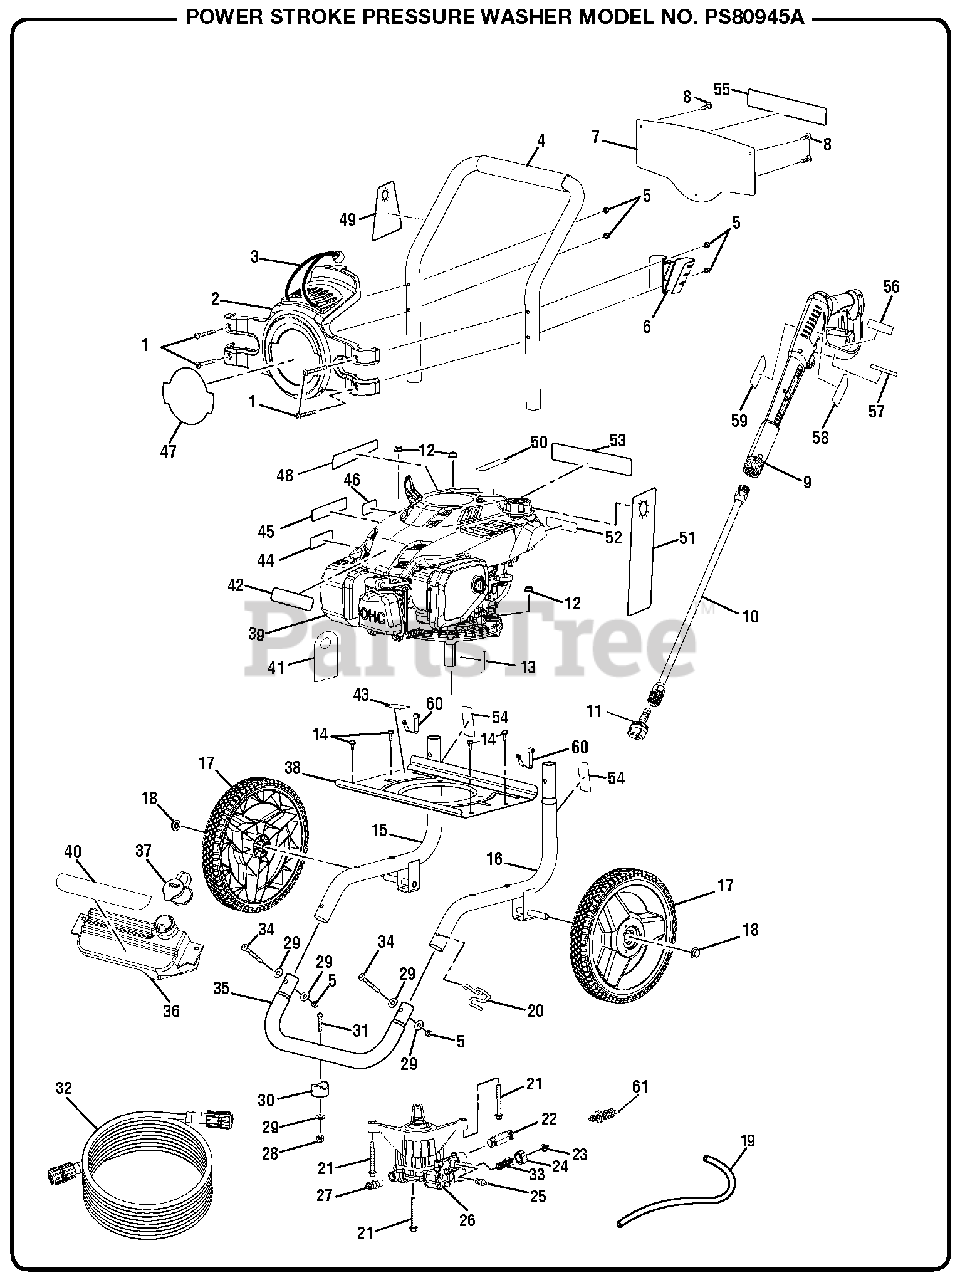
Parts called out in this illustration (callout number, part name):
1	Screw (M6 x 48 mm, T30 Torx Hd.)
2	Hose and Nozzle Holder Assembly
4	Handle w/Foam
5	Lock Nut (M6)
6	Wand Holder
7	Instruction Panel
8	Screw (#6-20 x 3/8 in., T10 Torx Pan Hd.)
9	Trigger Handle Assembly
10	Spray Wand Assembly
12	Flange Nut (M8 x 1.25)
13	Output Shaft Key (35 mm)
14	Bolt (M6 x 16 mm, Flange Hex Hd.)
15	Main Frame Assembly (RH)
16	Main Frame Assembly (LF)
18	Push Cap Nut (1/2 in.)
19	Chemical Siphon Tube
20	Lower Wand Holder
21	Bolt (M8 x 60 mm, Flange Hd.)
22	Outlet Tube
23	Inlet Filter Rubber Washer
24	Inlet Tube
25	Detergent Suction Kit
27	Thermal Release Valve
28	Lock Nut (1/4-20)
29	Washer (1/4 in.)
31	Screw (1/4-20 x 1.85 in., T30 Torx Hd.)
32	Hose (25 ft., 3100 psi)
33	Water Inlet Filter
34	Bolt (M6 x 55 mm, T30 Torx Hd.)
35	Front Frame
36	Soap Tank
37	Soap Tank Cap
38	Engine Plate
40	Soap Dilution Label
41	Dipstick Hang tag
42	Subaru Label
43	Engine Oil Fill Label
44	Combustion Label
45	Hot Surface Label
46	Lubricant Label
47	Performance Label
48	Pressure Relase Label
49	5- In- 1 Nozzle Hangtag
50	E85 Label
51	Danger Hangtag
52	Gas Only Label
53	Danger Label
54	Data Label
55	Quick Start Panel
56	Label (Trigger Handle Warning, French & Spanish)
57	Label (Trigger Handle Specifications)
58	Label (Trigger Handle Warning)
59	Label (Trigger Handle Logo)
60	Handle Spring Clip
61	Unloader Valve
